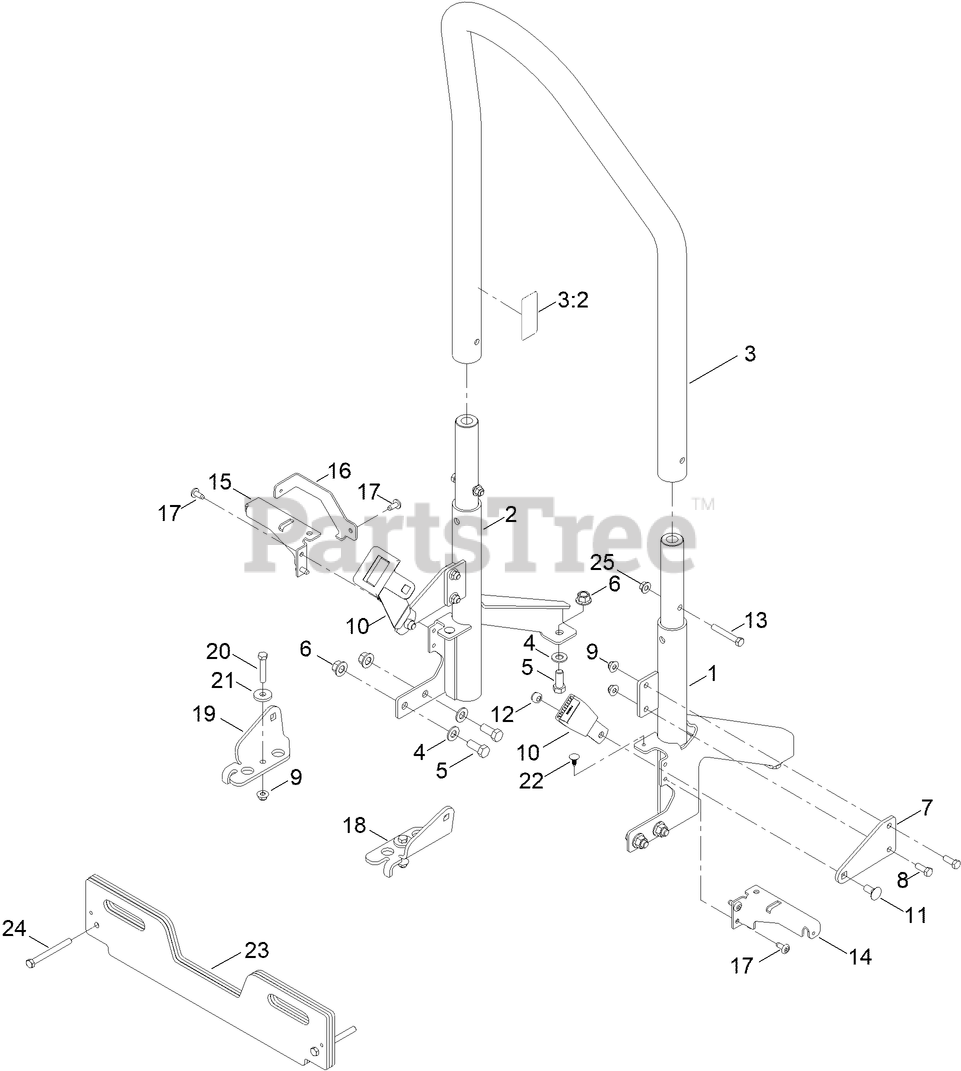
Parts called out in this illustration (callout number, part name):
1	MOUNT-ROPS, LH
2	MOUNT-ROPS, RH
3	UPPER ROPS ASM
3:2	DECAL-SAFETY, ROPS
4	WASHER-FLAT
5	SCREW-HH
6	NUT-HF
7	MOUNT - SEATBELT
8	SCREW-HH
9	NUT-HF, NI
10	BELT - SEAT
11	SCREW-CARR
12	NUT-HEX, NI
13	SCREW-HH
14	SUPPORT - POD LH
15	SUPPORT - POD, RH
16	POD - SUPPORT, RH W/MR
18	BRACKET - LH SEAT BELT
19	BRACKET - RH SEAT BELT
20	HHCS 3/8-16 X 2, GR5, CZ
21	WASHER
22	PLUG-PLASTIC
23	WEIGHT-BAGGER
24	SCREW-HH
25	NUT-FLANGE, LOCK
